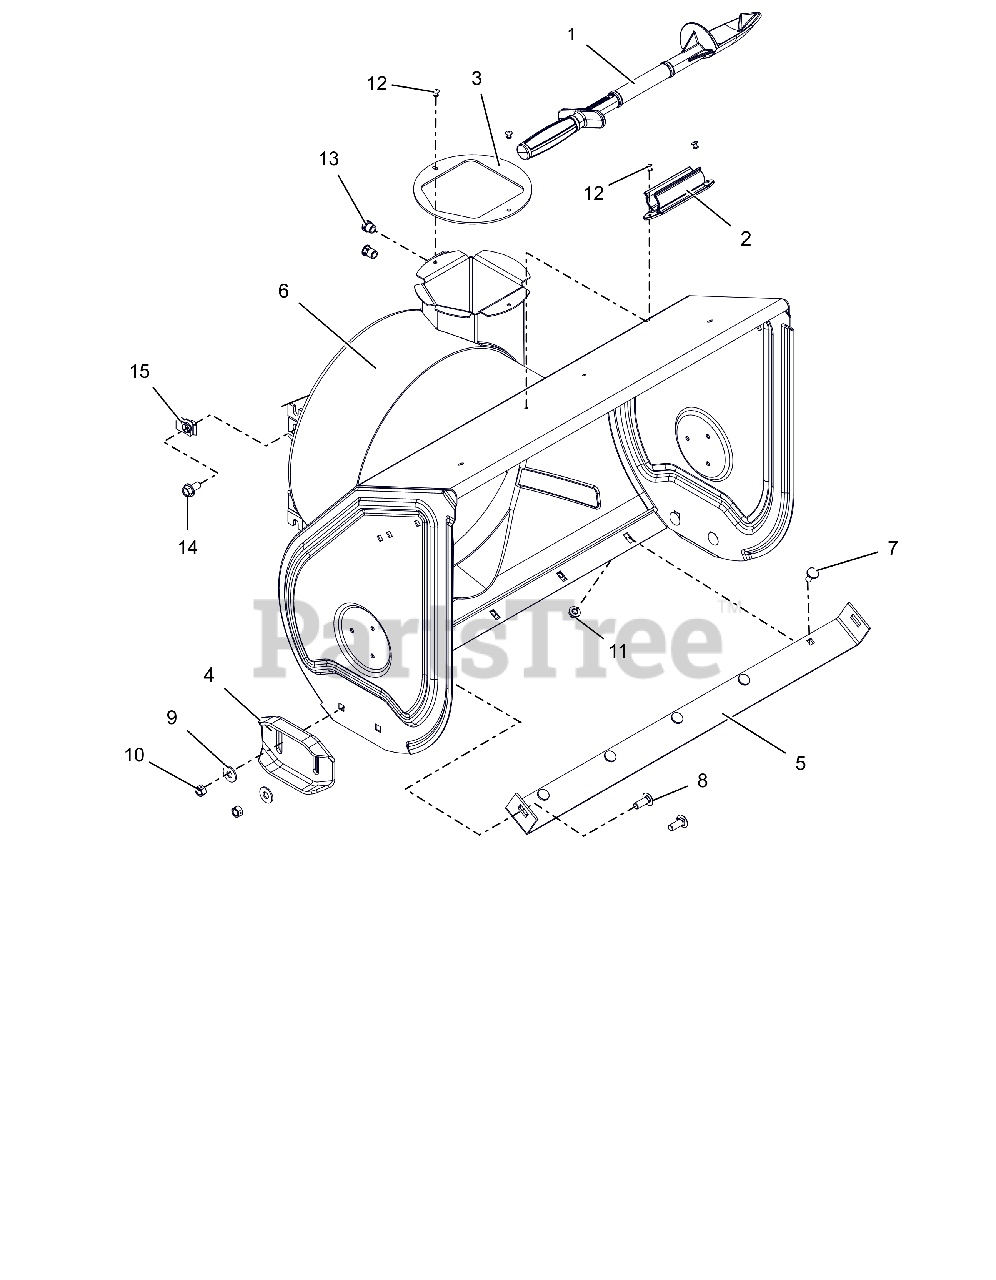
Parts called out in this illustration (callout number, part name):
1	DEVICE, SNOW CLEAN OUT
2	MOUNT, SNOW CLEAN OUT
3	BAFFLE, DISCHARGE NECK
4	SKID SHOE, REVERSIBLE - ORANGE
5	BLADE, SCRAPER - 28"
6	BLOWER HOUSING W/DECAL 28"
7	BOLT, MODIFIED HEAD CARRIAGE
8	@BLT-RDHDSHSQNK.38-16X1.0 G5YZ
9	@WSHR-FL-STL.438X1.00X.083 YWZ
10	@NUT-LK-CTR .38-16 YWZC
11	@NUT-LK-TOP-FLG .31-18 YWZC
12	RVT-POP .187 YZ
13	NUT, THREADED INSERT .38-16
14	BLT-SERHFWH .38-16X.75 YWZC
15	NUT-RTNR .375-16X.37
